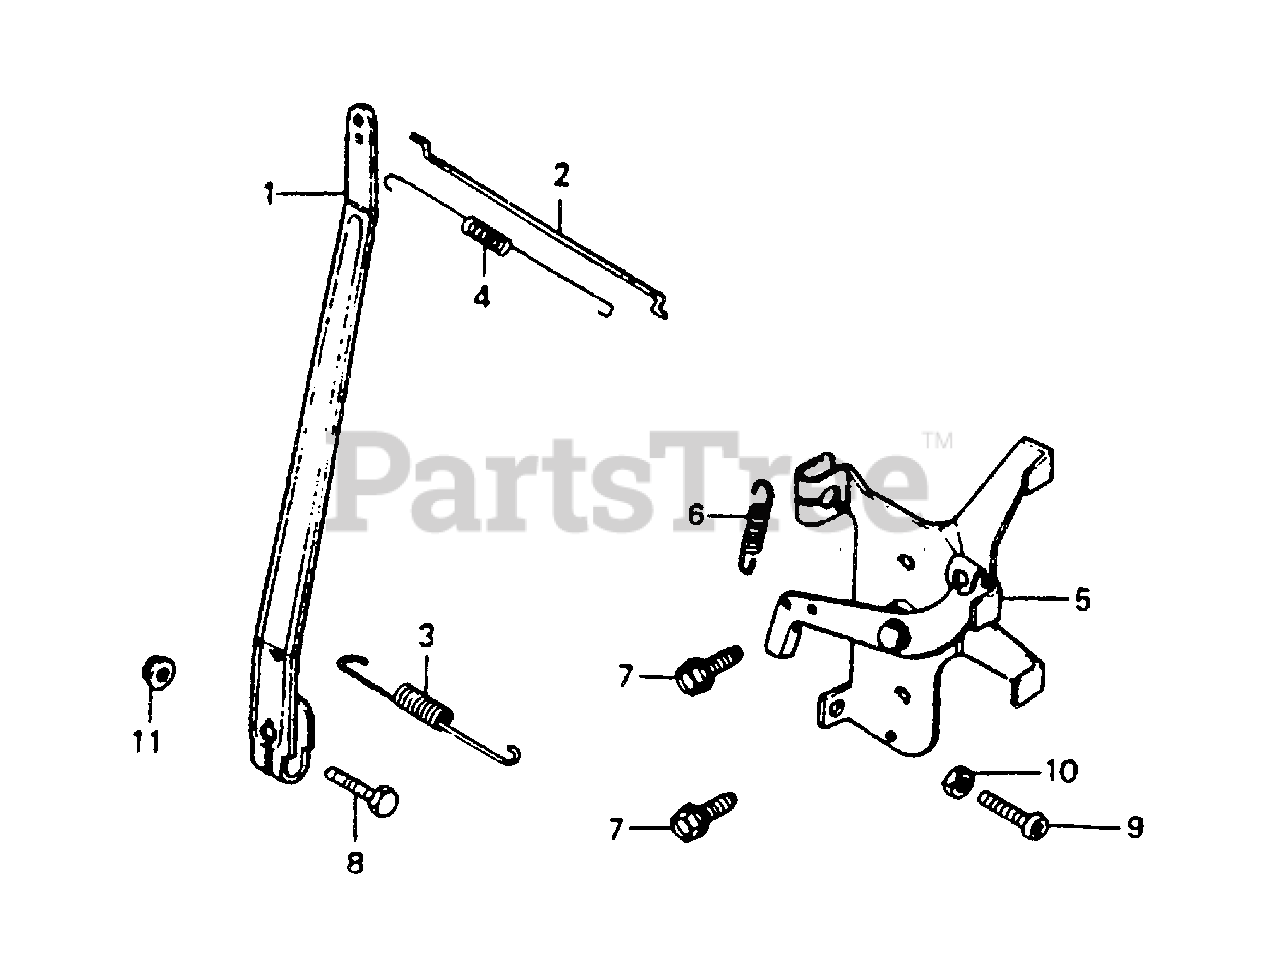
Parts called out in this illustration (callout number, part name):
1	ARM, GOVERNOR
2	ROD, GOVERNOR
3	SPRING, GOVERNOR
4	SPRING, THROTTLE RETURN
5	LEVER, CONTROL
6	SPRING, CABLE RETURN
7	BOLT, FLANGE (6X12) (CT200)
8	BOLT, HEX. (6X20)
9	SCREW, PAN (6X20)
9	SCREW, PAN (6X25)
10	NUT, HEX. (6MM)
11	NUT, FLANGE (6MM)
